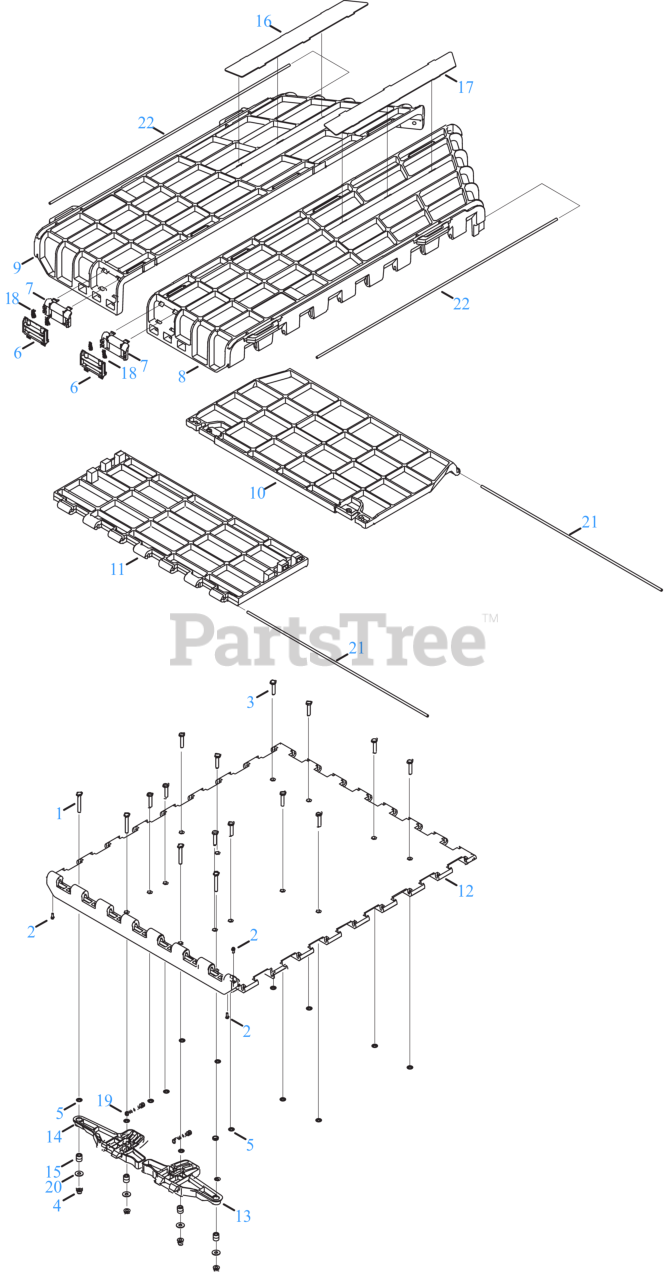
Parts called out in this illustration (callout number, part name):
1	HEX SCREW 5/16-18 x 2.25 GR5
2	SCREW #8-16 x .50
3	SCREW 5/16-18 x 1.5 LG
4	FLANGE LOCK NUT 5/16-18
6	PANEL LATCH
7	RETAINING PANEL LATCH
8	SIDE PANEL-LEFT
9	SIDE PANEL- RIGHT
10	TAILGATE PANEL
11	FRONT PANEL
12	BASE PANEL
13	DOOR RELEASE LEVER (RH)
14	DOOR RELEASE LEVER (LH)
15	LEVER SPACER
16	LABEL PLATE - LEFT
17	LABEL PLATE - RIGHT
18	COMPRESSION SPRING
19	COMPRESSION SPRING
20	FLAT WASHER
21	HINGE ROD .25 x 27.7
22	HINGE ROD .25 x 36.8
